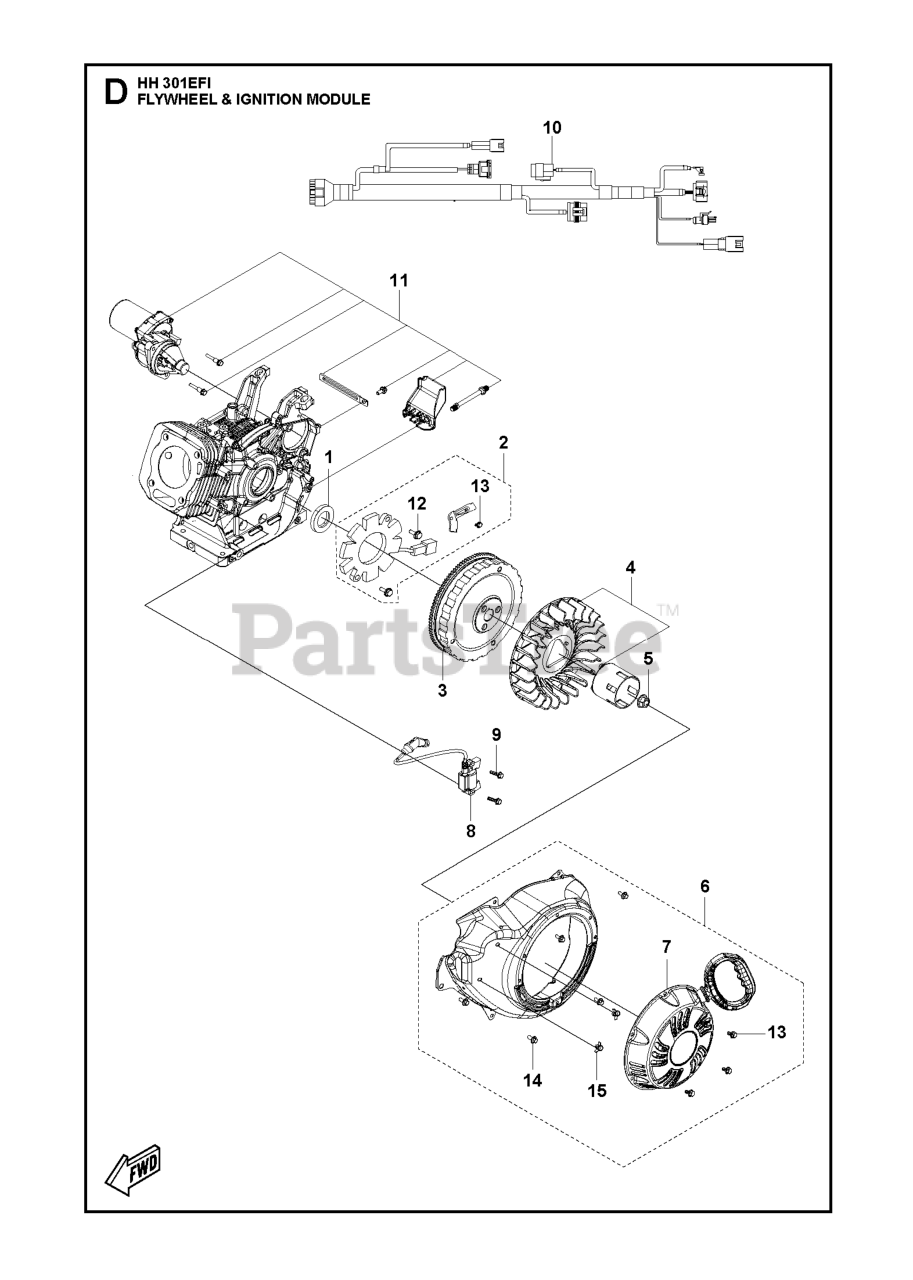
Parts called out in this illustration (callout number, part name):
1	SEAL OIL SEAL
2	COIL CHARGE COIL KIT
6	STARTER ASSY
7	STARTER HANDLE ASSY
8	IGNITION COIL
10	WIRE ECU WIRE
11	STARTER MOTOR
13	BOLT
14	BOLT
